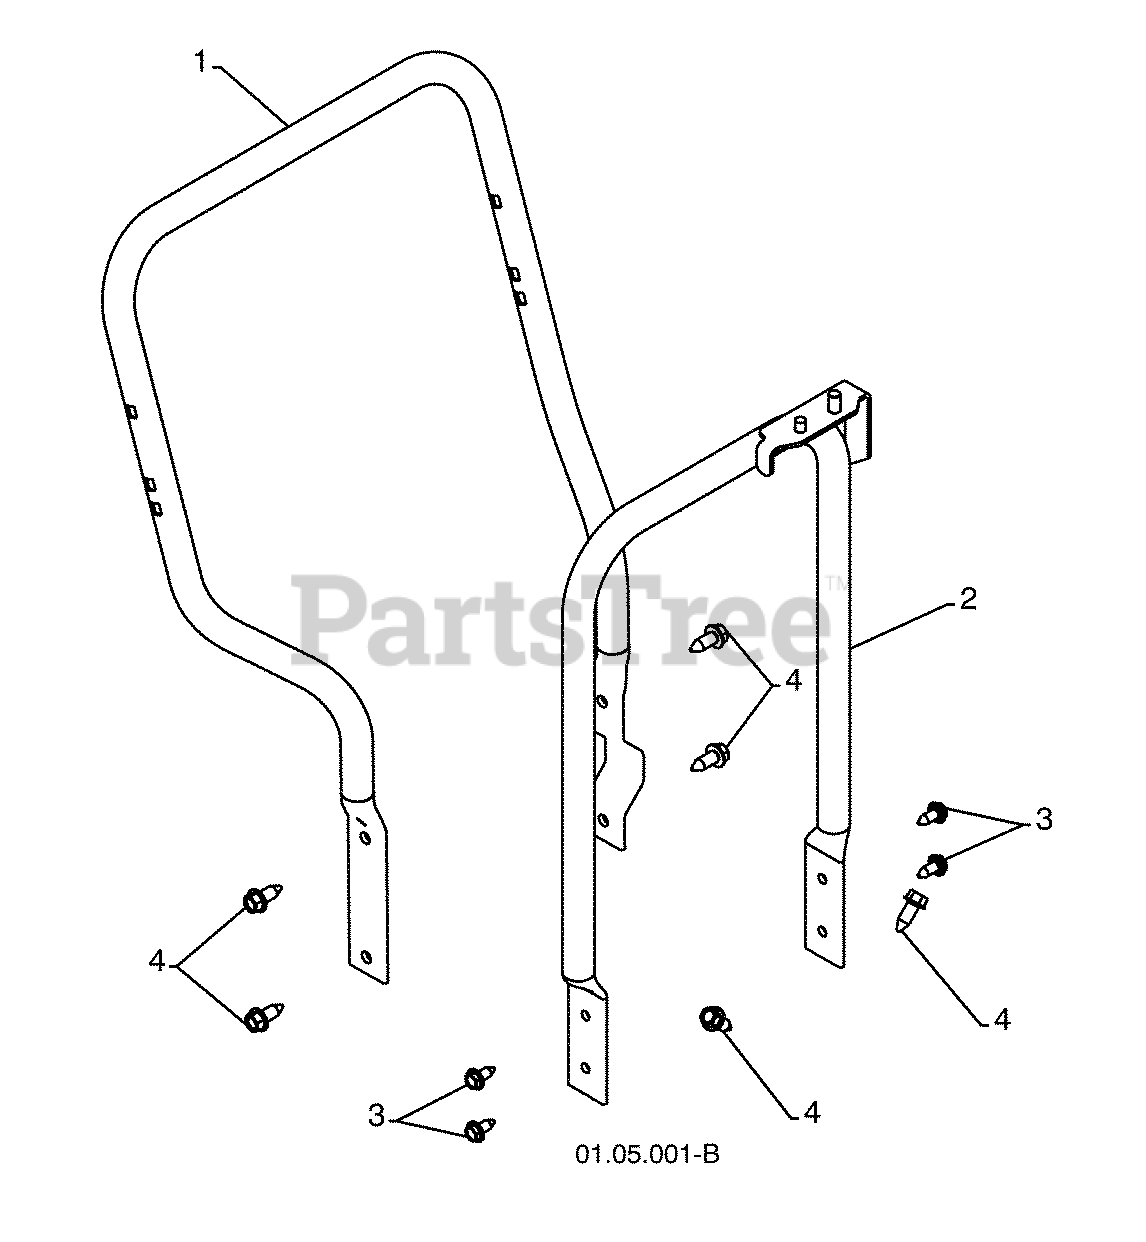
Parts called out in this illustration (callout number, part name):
1	LOWER TUBE
2	PIVOT SUPPORT
3	BOLT 5/16-18 X .750
4	SCREW 3/8-16 X 1.00
